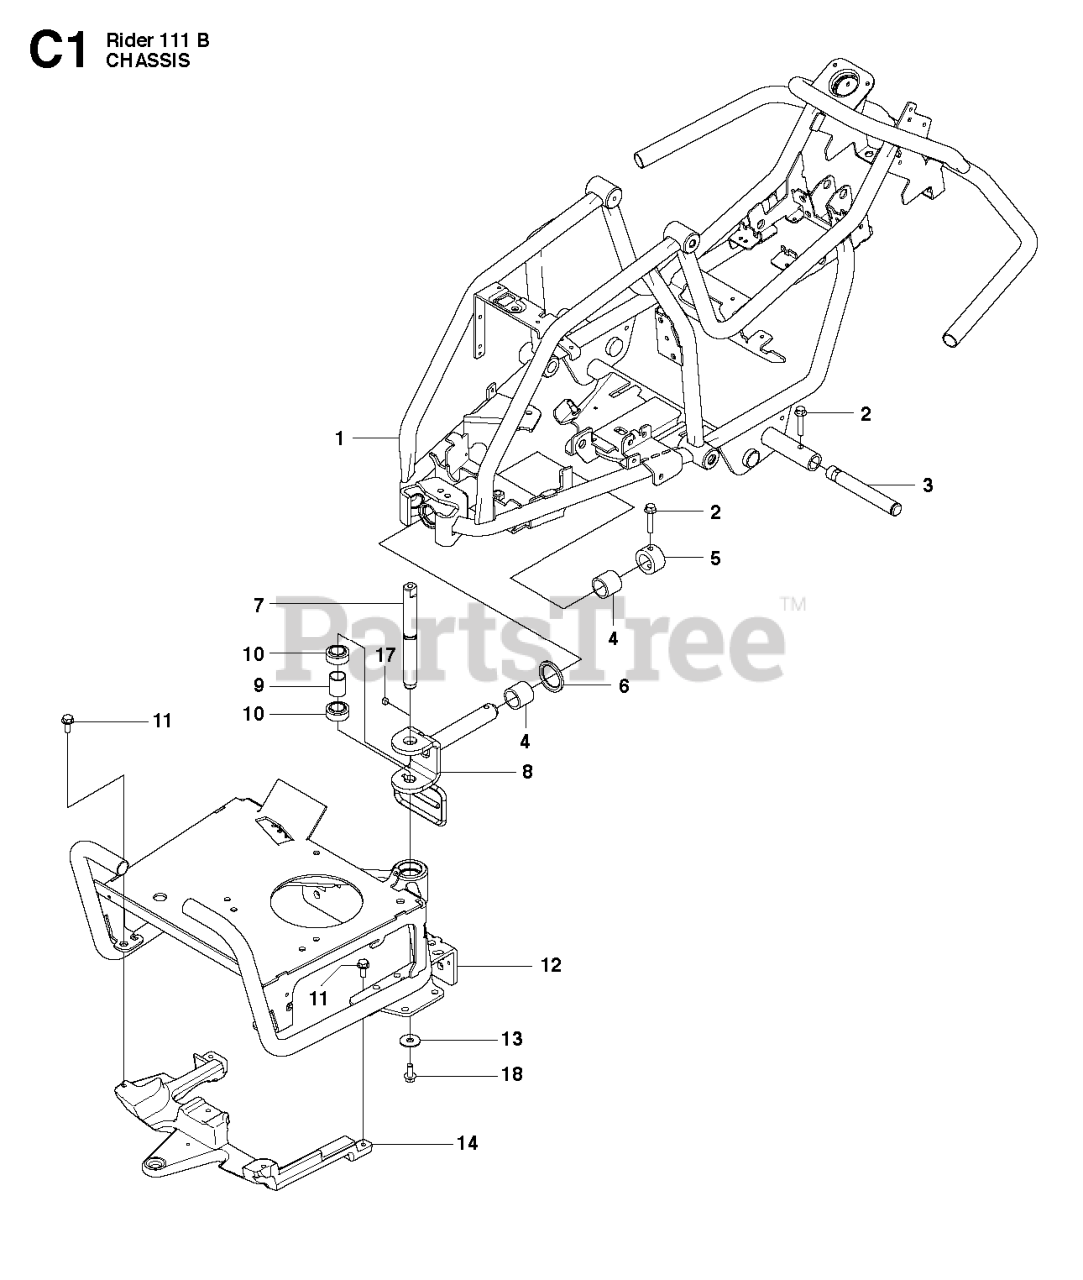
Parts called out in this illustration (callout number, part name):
2	BOLT FLANGE - M8X40\
4	BUSHING
5	STOP SLEEVE
